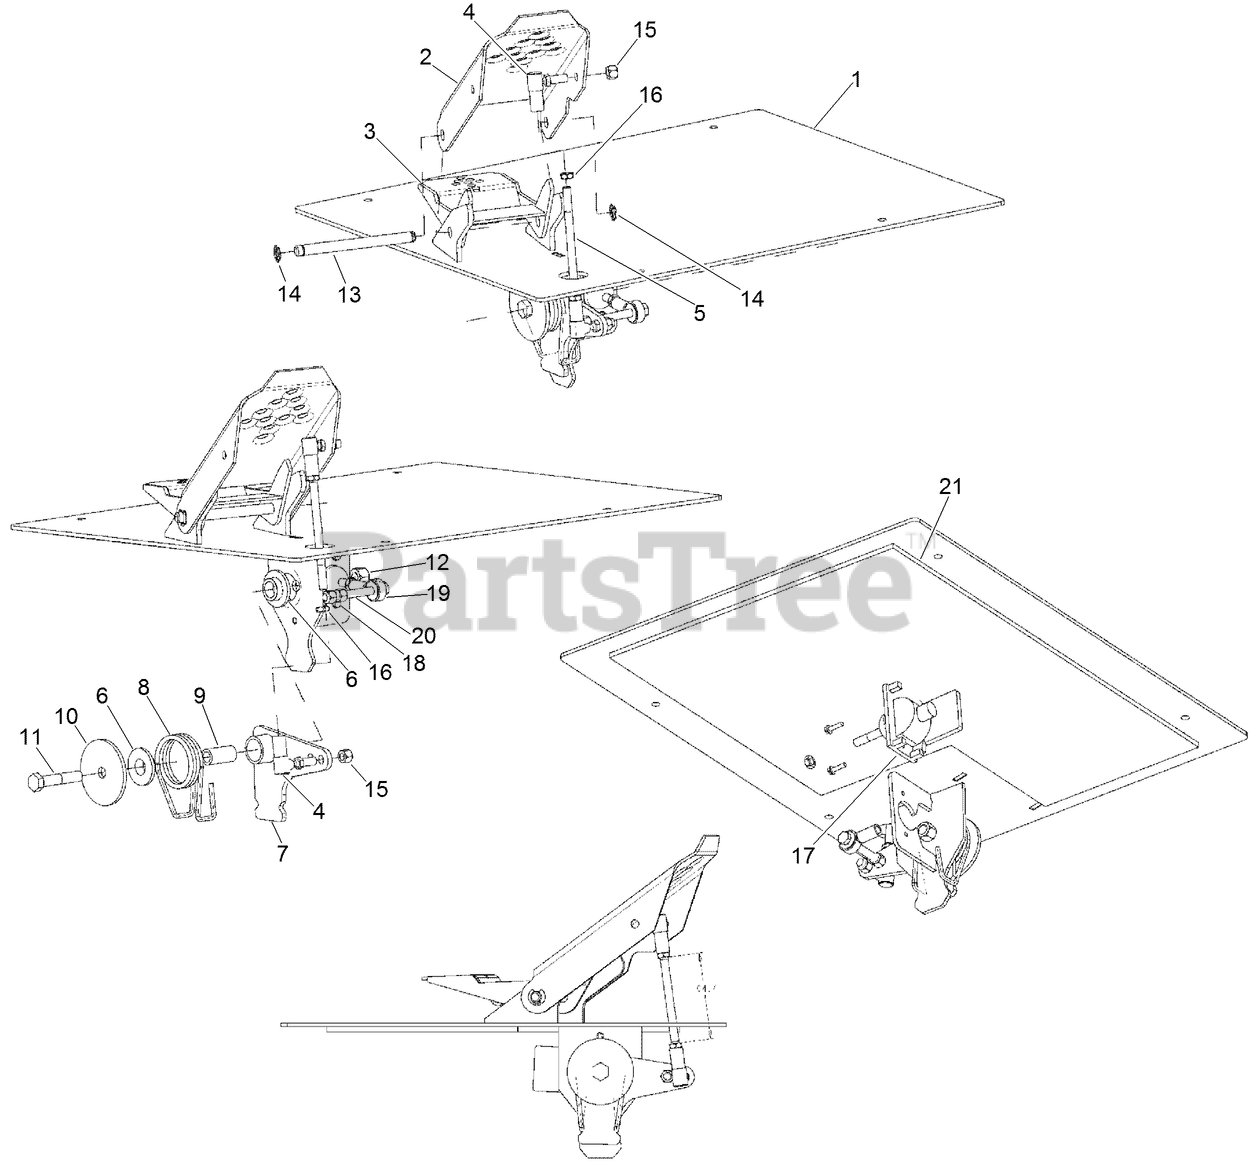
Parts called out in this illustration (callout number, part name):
1	PLATE - Floor
2	PEDAL - Ground Drive
3	PEDAL WELDMENT - Heel
4	JOINT-BALL
5	ROD-CONTROL
6	BUSHING-INSERT, PLASTIC
7	PIVOT-W/BELLCRANK
10	WASHER-Special
11	SCREW-HH
12	NUT-HEX
14	RING-Klip 1/2 inch
15	NUT-HEX
16	NUT-JAM, HEX
17	JOYSTICK AND CONNECTOR - Single Axis (P&Q Controls)
18	SCREW-HWH
19	BEARING - Spherical Rod End
20	BOLT - Hex Hd .375 x 3.50 GR5 ZND
21	INSULATION-FLOOR
